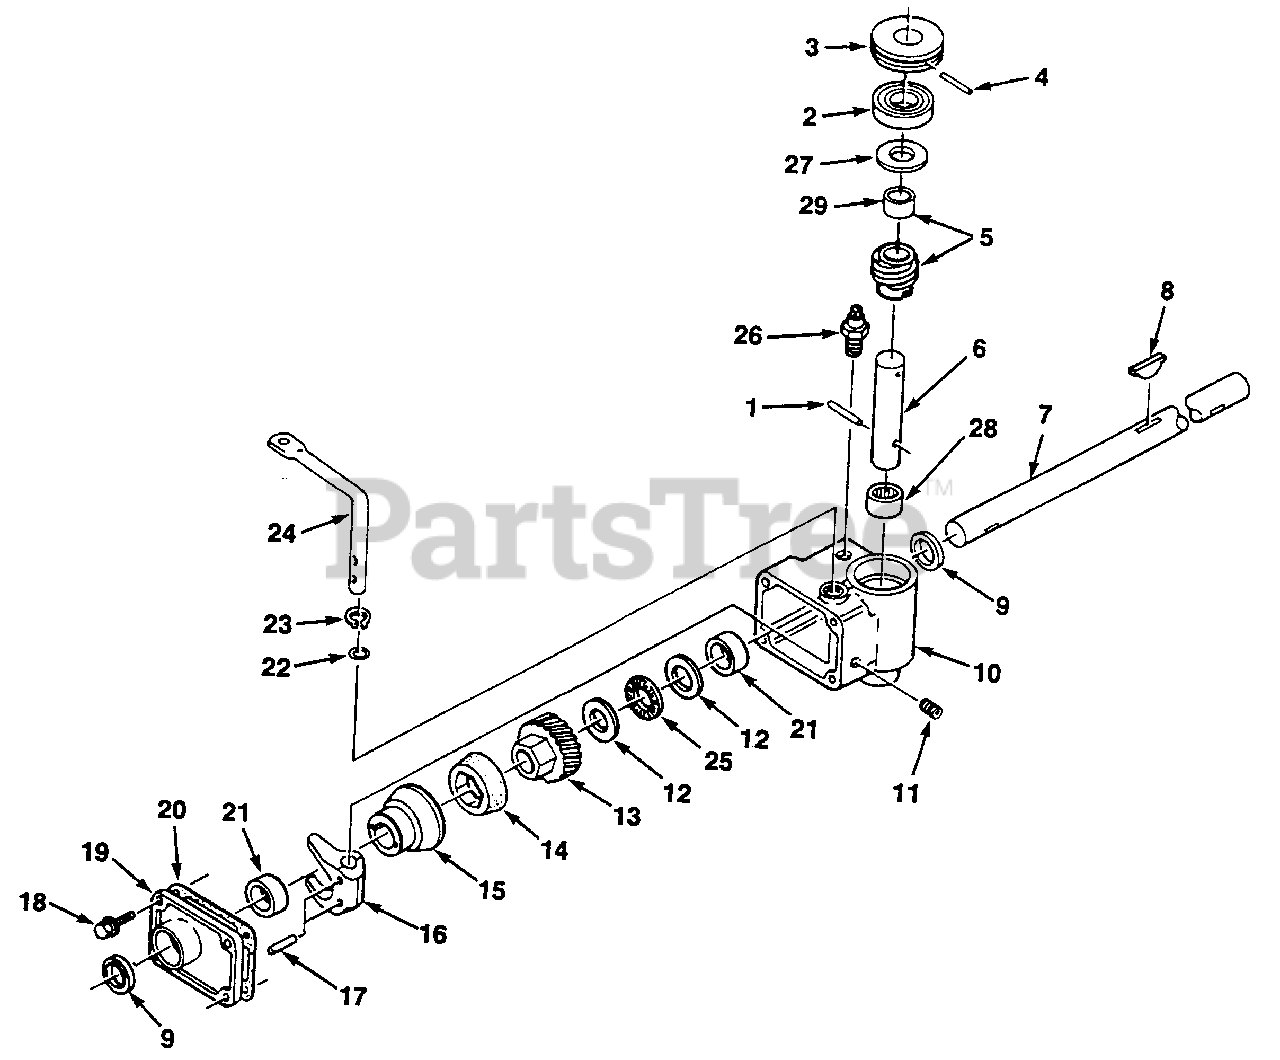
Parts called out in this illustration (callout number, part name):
1	PIN- (3/16 x 7/8")
3	PULLEY
4	PIN- (3/32 x 3/4")
5	WORM & SPACER-
6	SHAFT- Worm
7	SHAFT- Drive
8	KEY- (1/2-1/8")
10	GEAR REDUCER HOUSING ASSY.
12	RACE- Bearing
13	GEAR- Helical
14	CONE- Friction
15	DRUM- Clutch
16	FORK- Shift
17	PIN- (5/32 x 3/4")
18	SCREW- (1/4-20 x 7/8")
19	COVER- Gearbox
20	GASKET
21	BUSHING- Sleeve
23	RING- Eaton
24	LEVER- Shift
25	BEARING- Thrust
28	BEARING- Needle
29	SPACER- Worm gear
